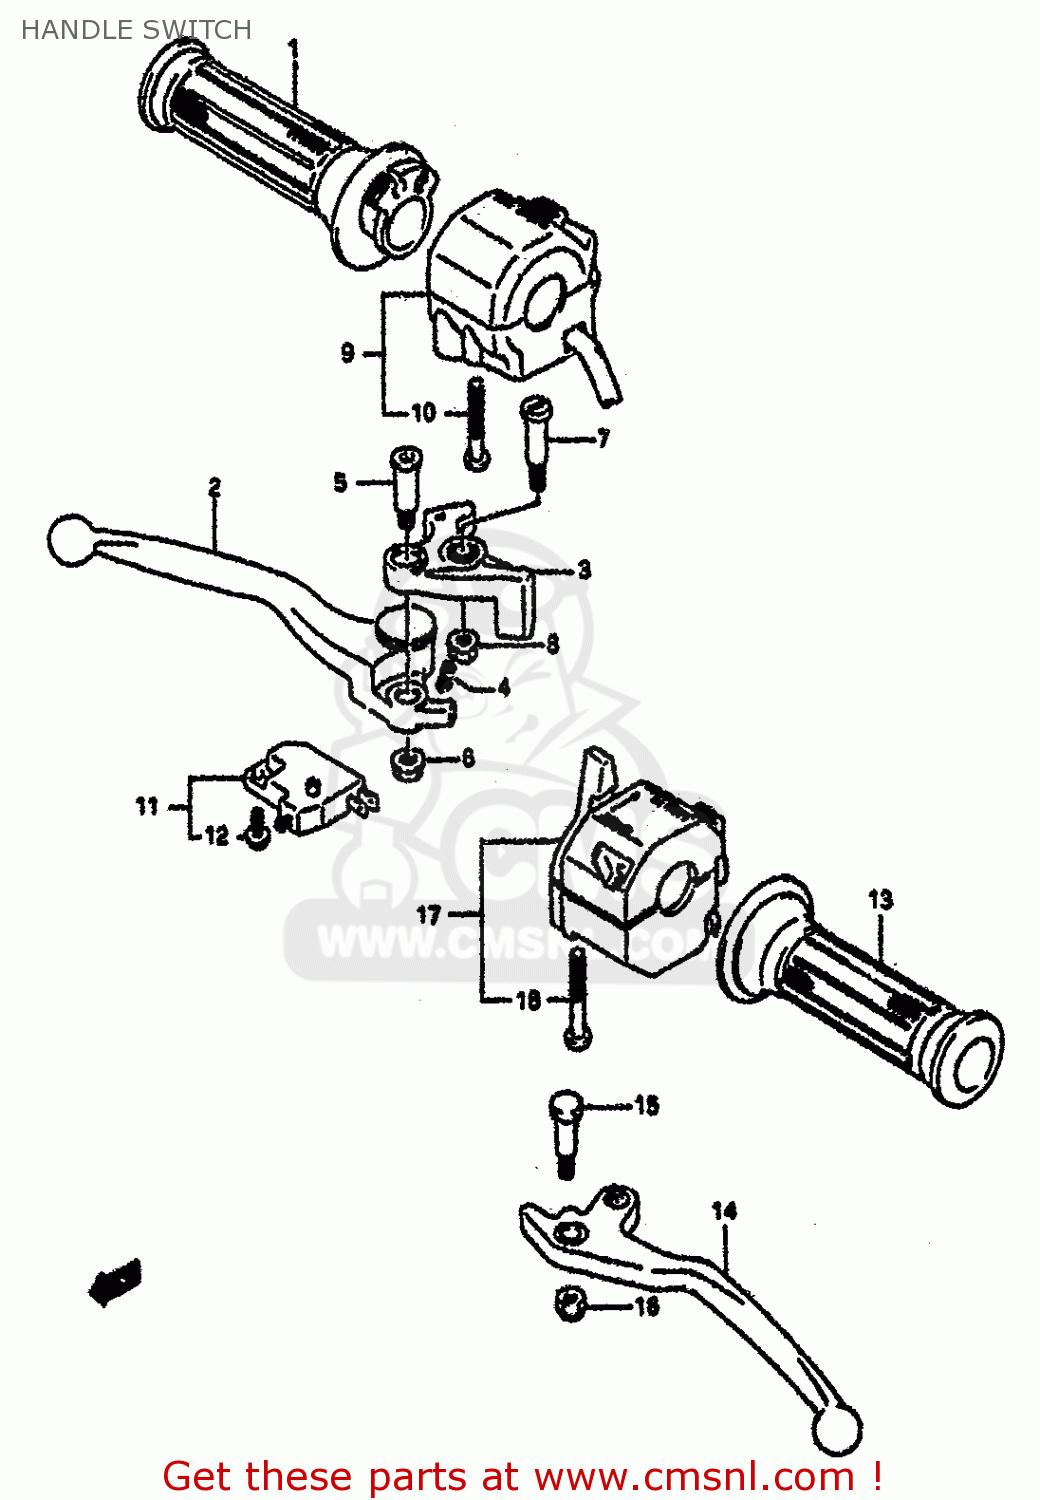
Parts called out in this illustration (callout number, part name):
1	GRIP,THROTTLE
2	LEVER,ADJUST
3	KNOCKER
4	SPRING
5	BOLT,LEVER
6	NUT
7	BOLT,LEVER PIVOT
8	NUT 6MM
9	SWITCH,HANDLE,
10	SCREW, 5X45
11	SWITCH ASSEMBLY,STOP
12	SCREW
13	GRIP,L
14	LEVER,CLUTCH (SILVER)
15	BOLT,LEVER
16	NUT
17	SWITCH ASSY,L
18	SCREW, 5X45
